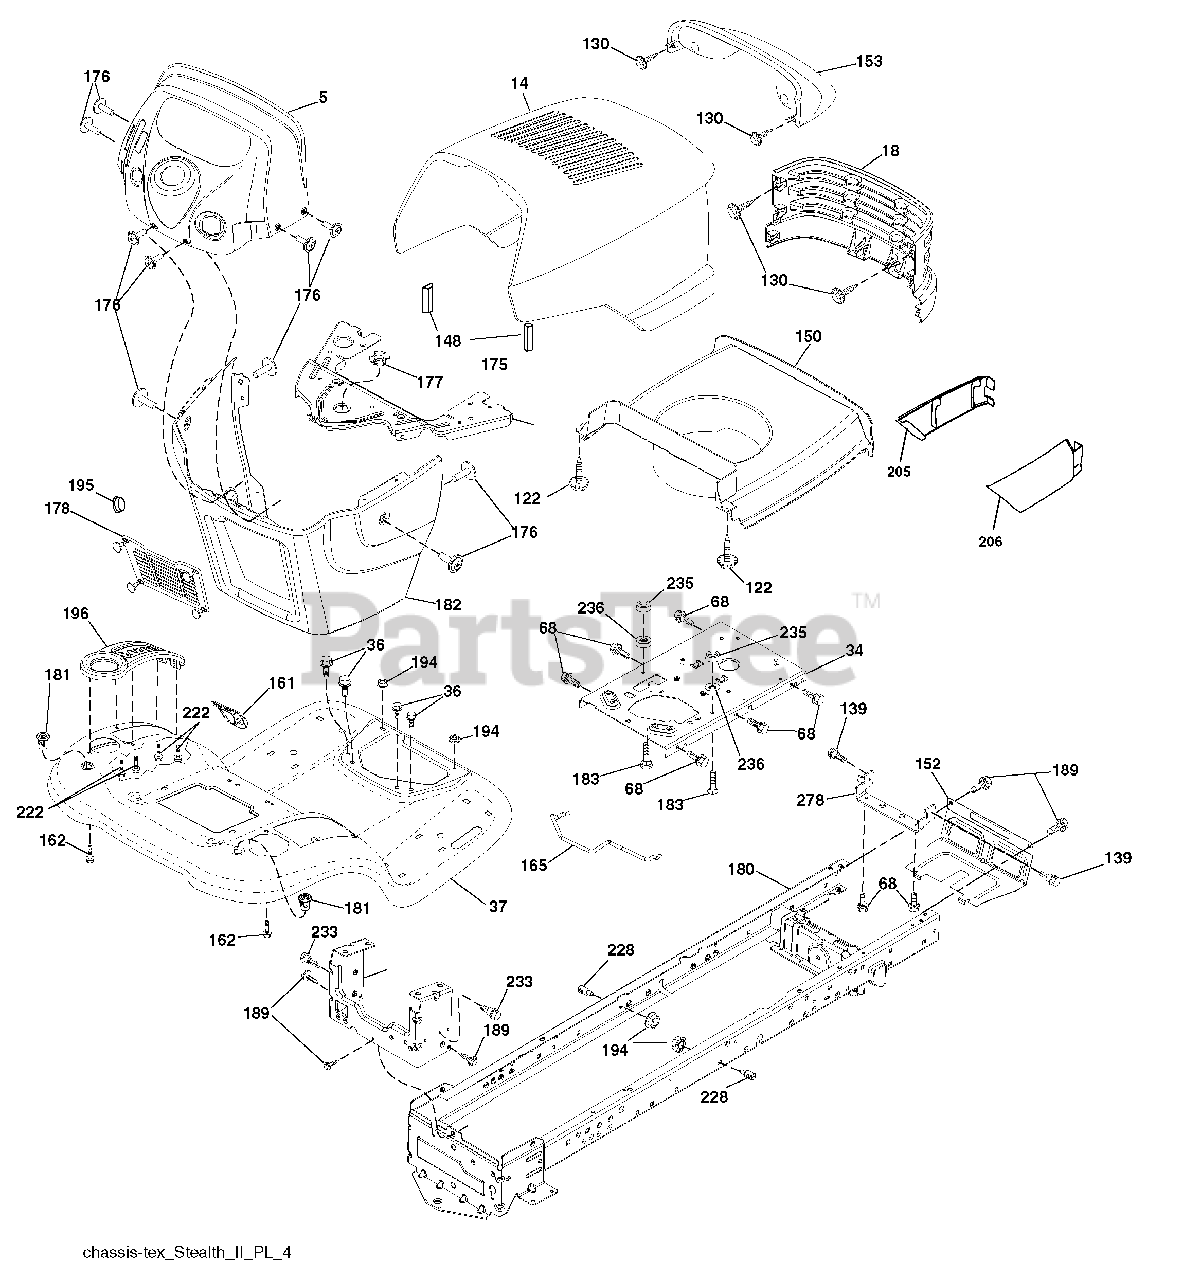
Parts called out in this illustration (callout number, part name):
5	Dash
14	Hood
18	Grille
34	Plate Engine
36	Screw 5/16-18 x 3/4
37	Fender
58	Drawbar Upper
68	Screw 5/16-18 x 1/2
122	Screw WSHD Hex 10-32 x 5/8
130	Screw #10 x 0.750 BOS Thread
139	Bolt Shoulder 5/16 - 18
148	Bumper Hood
150	Duct Heat
152	Shield Browning/Debris
153	Lens Bar
161	Window Fuel
162	Screw Hex Wsh Hi-Lo 1/4 x 1/2 unc
165	Bracket Support Tank
175	Cross Member
176	Screw 10-24 x 5/8 Wshd. Qdrx.
177	Bushing Steering
178	Cargo Asm. Net
180	Chassis
181	Bushing Mtg. Fender Crgo.
182	Dash Lower
183	Bolt Fin. Hex 5/16-18 x 1-1/4
189	Screw 5/16-18 x 3/4
194	Nut Lock Hex Flange 5/16-18
195	Plug Hole Dash
196	Console Asm. Deck Lift
205	Skirt Hood RH
206	Skirt Hood LH
222	Screw Thrdrol. 1/4-20 x 5/8
228	Stud Fastener
233	Bolt Shoulder
235	Spacer Fender
236	Nut Lock 5/16-18
278	Bracket Hood Muff
